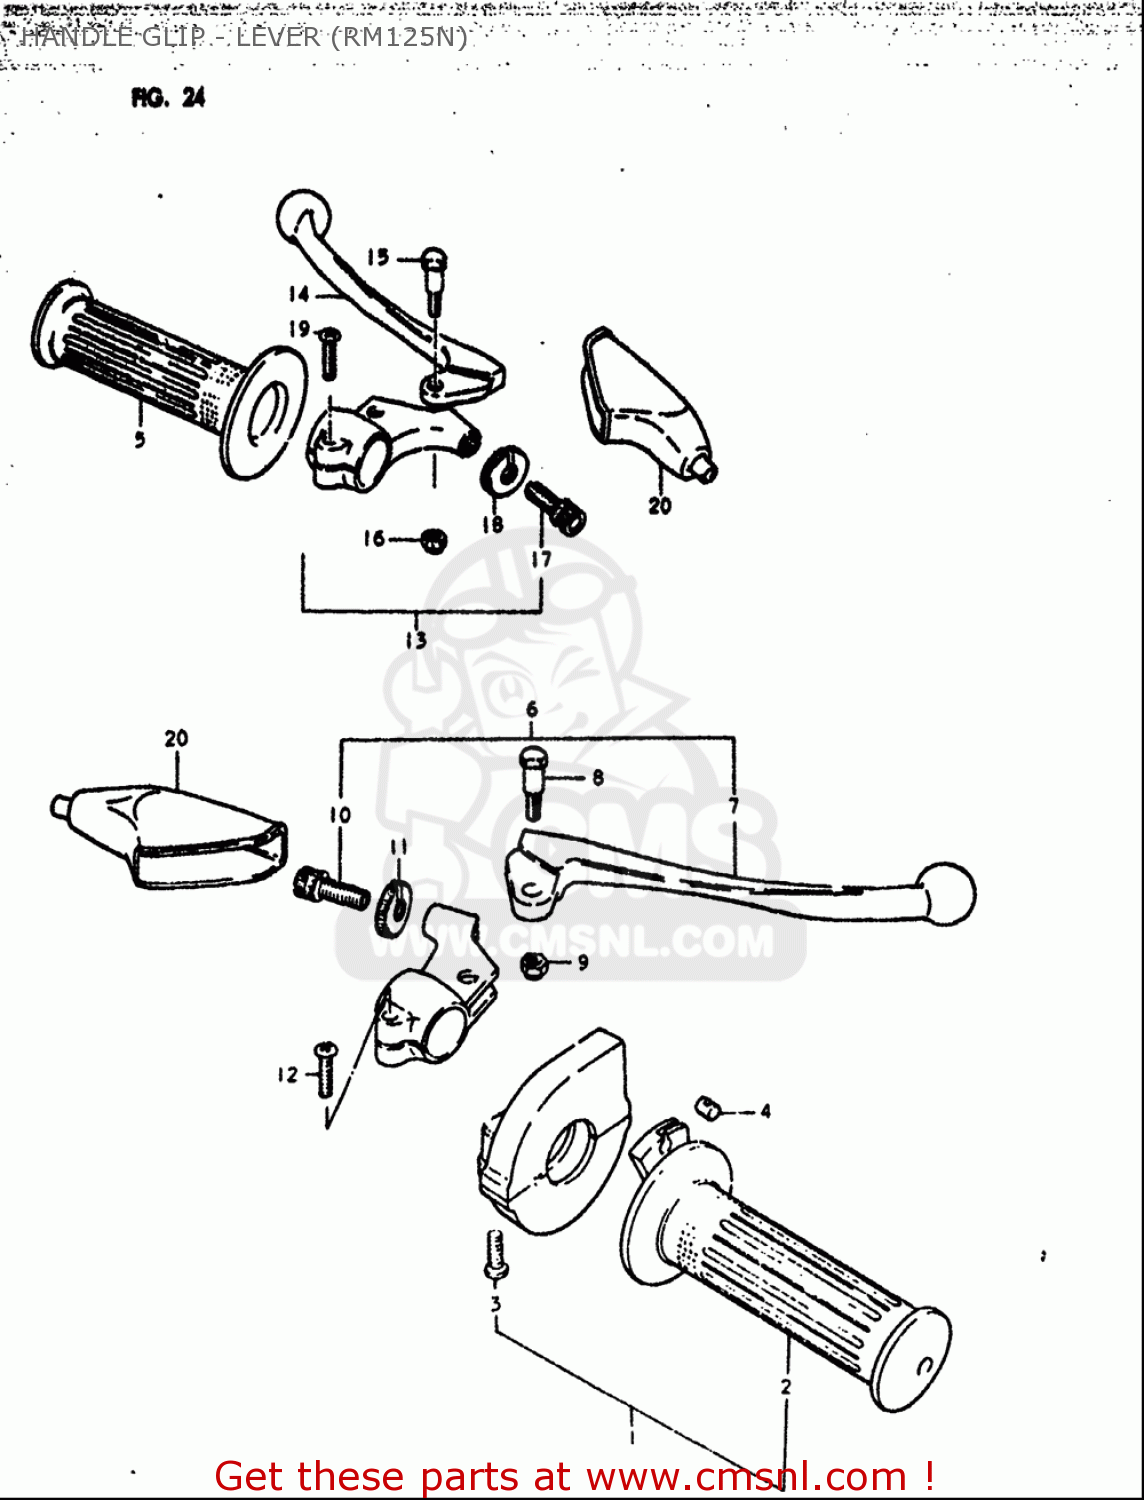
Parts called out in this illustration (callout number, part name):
1	GRIP ASSY,THROTTLE
2	GRIP,THROTTLE
3	SCREW
4	PIECE,THROTTLE END
5	GRIP,L
6	LEVER ASSY,BRAKE
7	LEVER,BRAKE
8	BOLT,LEVER PIVOT
9	NUT 6MM
10	ADJUSTER,CABLE
11	NUT,CABLE ADJUSTER
12	SCREW
13	LEVER ASSY,CLUTCH
14	LEVER,CLUTCH
15	BOLT,LEVER PIVOT
16	NUT 6MM
17	ADJUSTER,CABLE
18	NUT,CABLE ADJUSTER
19	SCREW
20	COVER,CLUTCH LEVER
